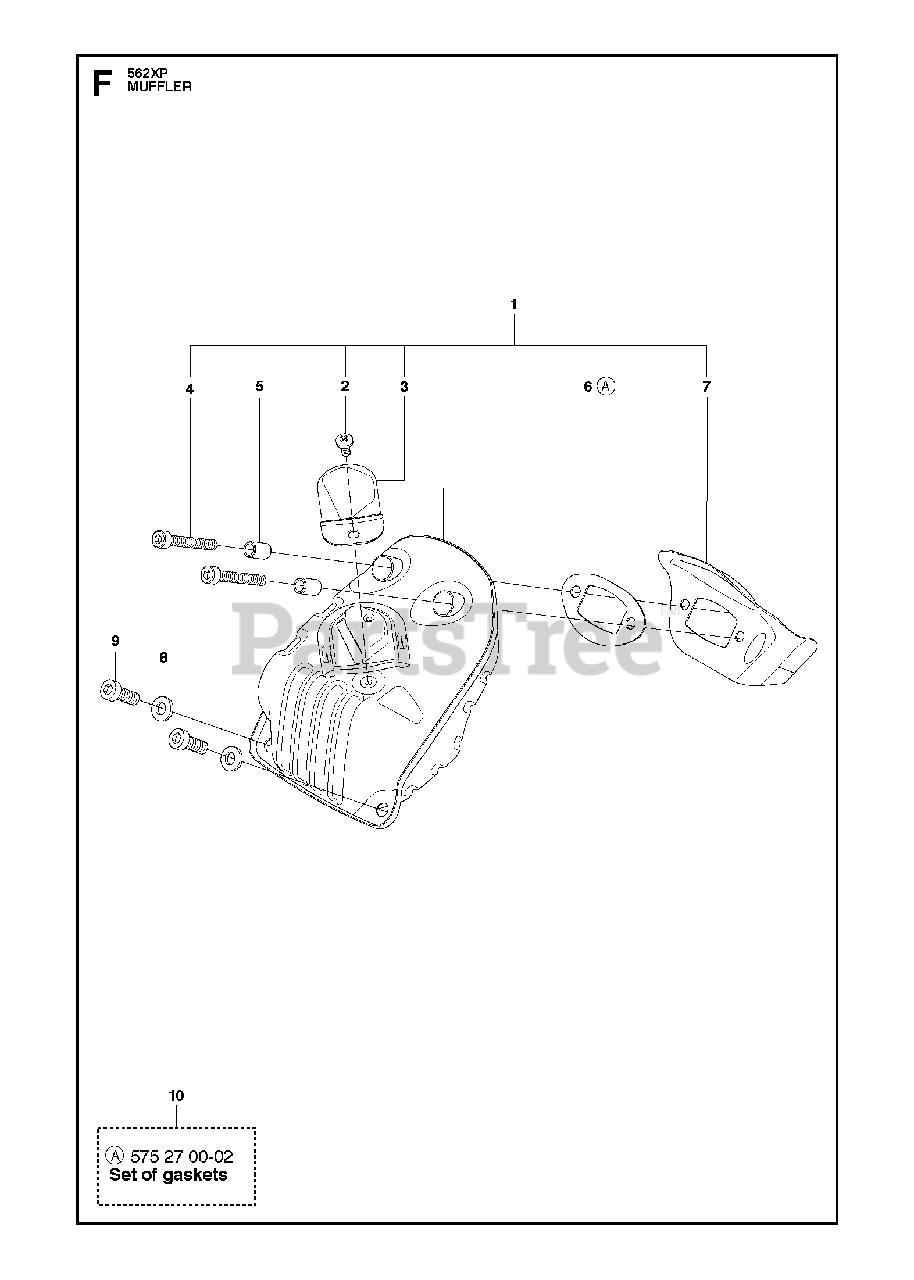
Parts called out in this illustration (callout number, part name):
1	MUFFLER KIT
2	SCREW
3	SPARK ARRESTER
4	SCREW
5	SLEEVE MUFFLER
6	GASKET MUFFLER
7	HEAT DEFLECTOR
8	WASHER
10	GASKET KIT
